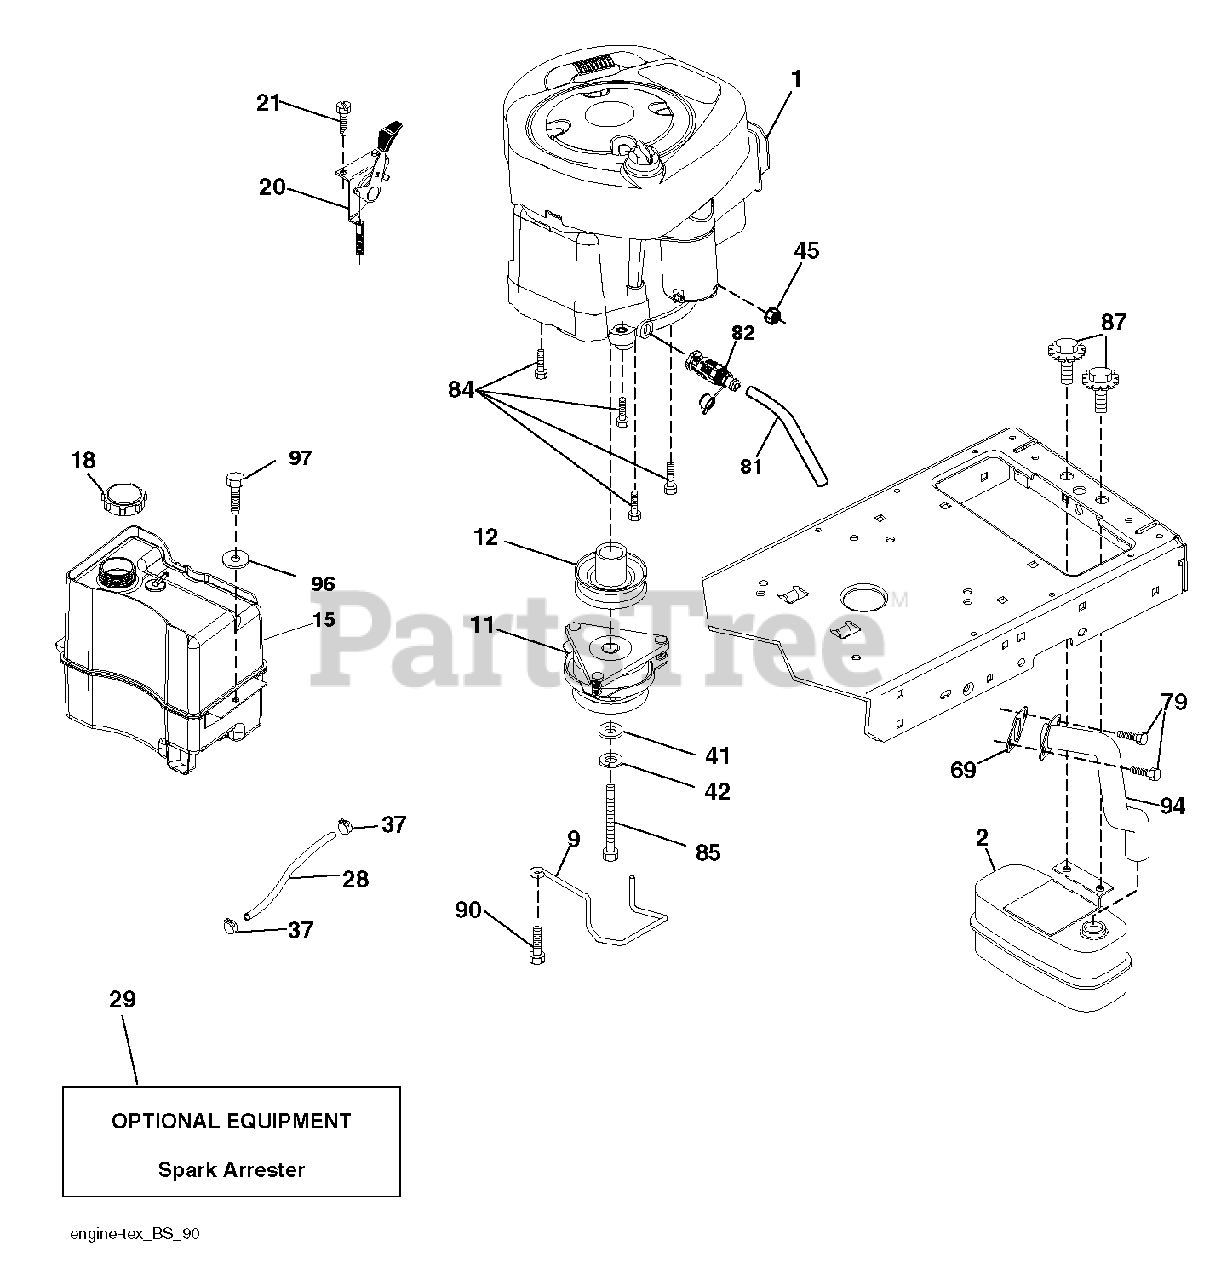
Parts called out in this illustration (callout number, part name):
2	MUFFLER.SINGLE.LRG.BRIGGS.KOHL
9	KEEPER BELT ENGINE
11	RB.CLUTCH.OGURA.4.4.PD
12	PULLEY.ENGINE.TUFFTORQ
15	FUEL.TANK.ASM.NON-EPA
18	CAP ASM.FUEL.2.25"FR.
20	CONTROL.TH/CK.C.
21	SCREW.#10 X 0.750.BOS
28	LINE.FUEL.20
29	KIT.SPARK ARRESTOR 794945 B&S
37	HOSE CLAMP
42	LOCKWASHER
45	NUT
69	REPL BY 532 27 22-93
79	SCREW.SOCKET HD.5/16-1
81	TUBE, DRAIN OIL ASM.
82	VALUE.OIL.DRAIN
84	SCREW.3/8-16
85	BOLT HEX 7/16-20X4-1/4"
87	BOLT, 5/16-18 X 1 3/4
90	SCREW 3/8-16X1
94	EXHAUST.TUBE.B&S.28/31
97	SCREW HEXWSHR 1/4-20X3/4
